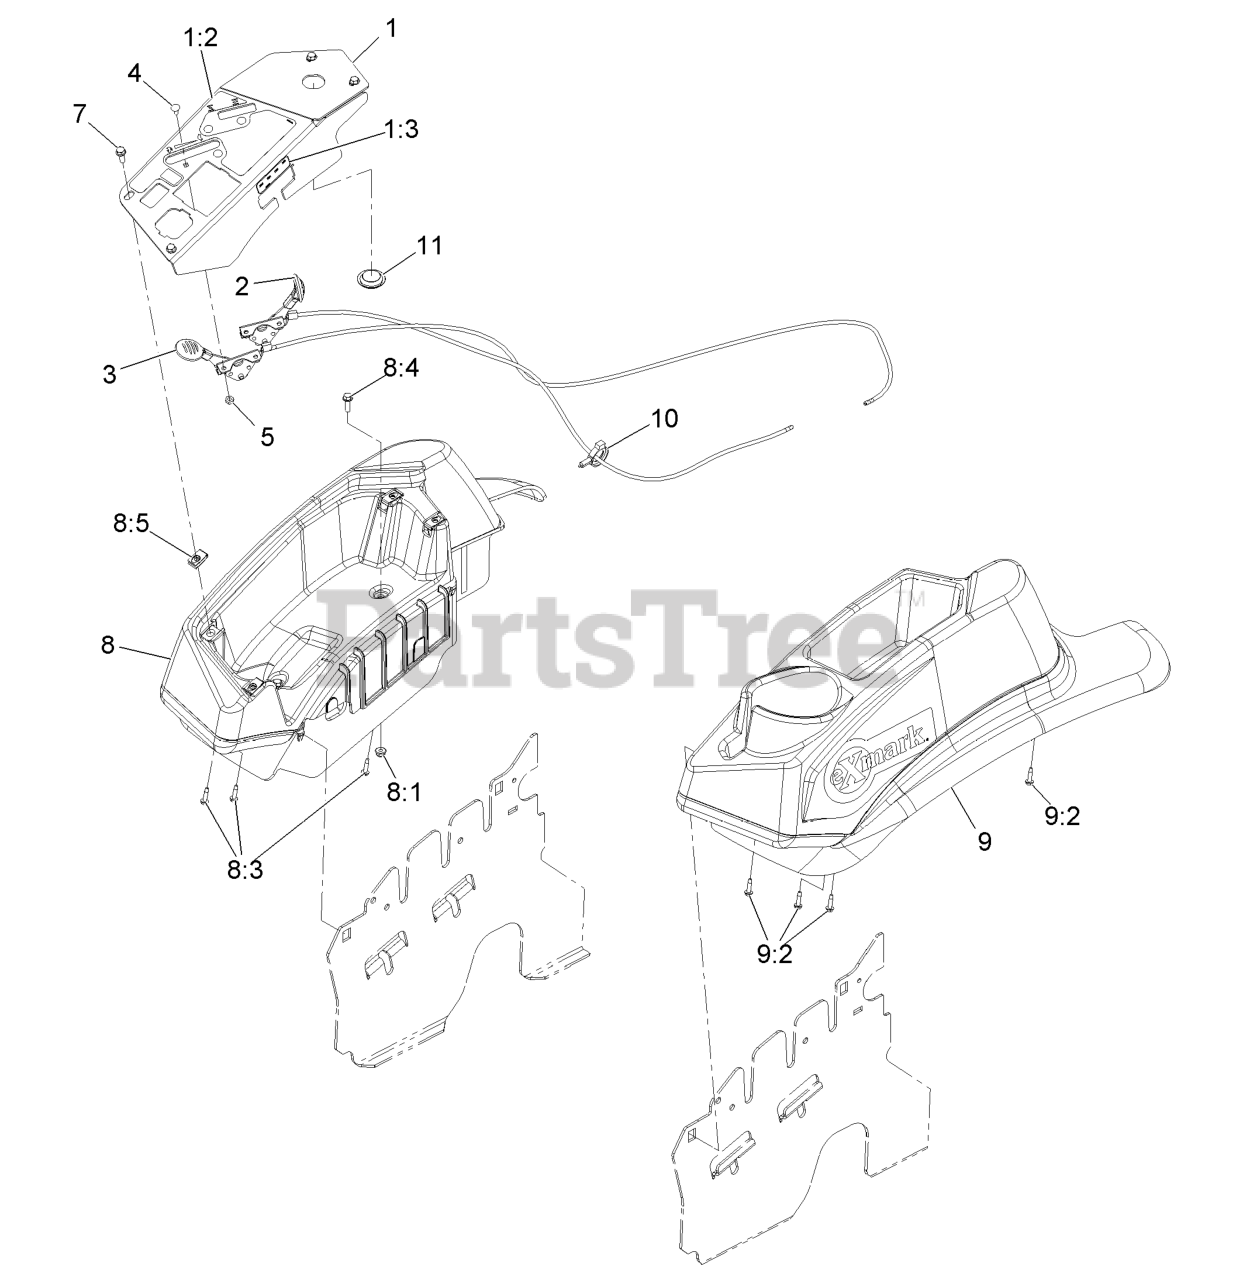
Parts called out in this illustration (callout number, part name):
1	ASM,CONSOLE PANEL W/DECAL
1:2	DECAL-CONTROL PANEL
1:3	DECAL-FUSE
2	ASM, CHOKE CABLE
3	ASM,THROTTLE CABLE
4	BOLT-CARR
5	NUT-LOCK, NI
7	SCREW-HWH
8	CONSOLE,RH NARROW ASM
8:3	SCREW,THD FORM,HWH
8:4	SCREW-HWH
8:5	Nut-Retainer-Panel 1/4-20
9	CONSOLE.LH NARROW ASM
9:2	SCREW,THD FORM,HWH
10	CLAMP-HOSE
11	PLUG-PLASTIC
